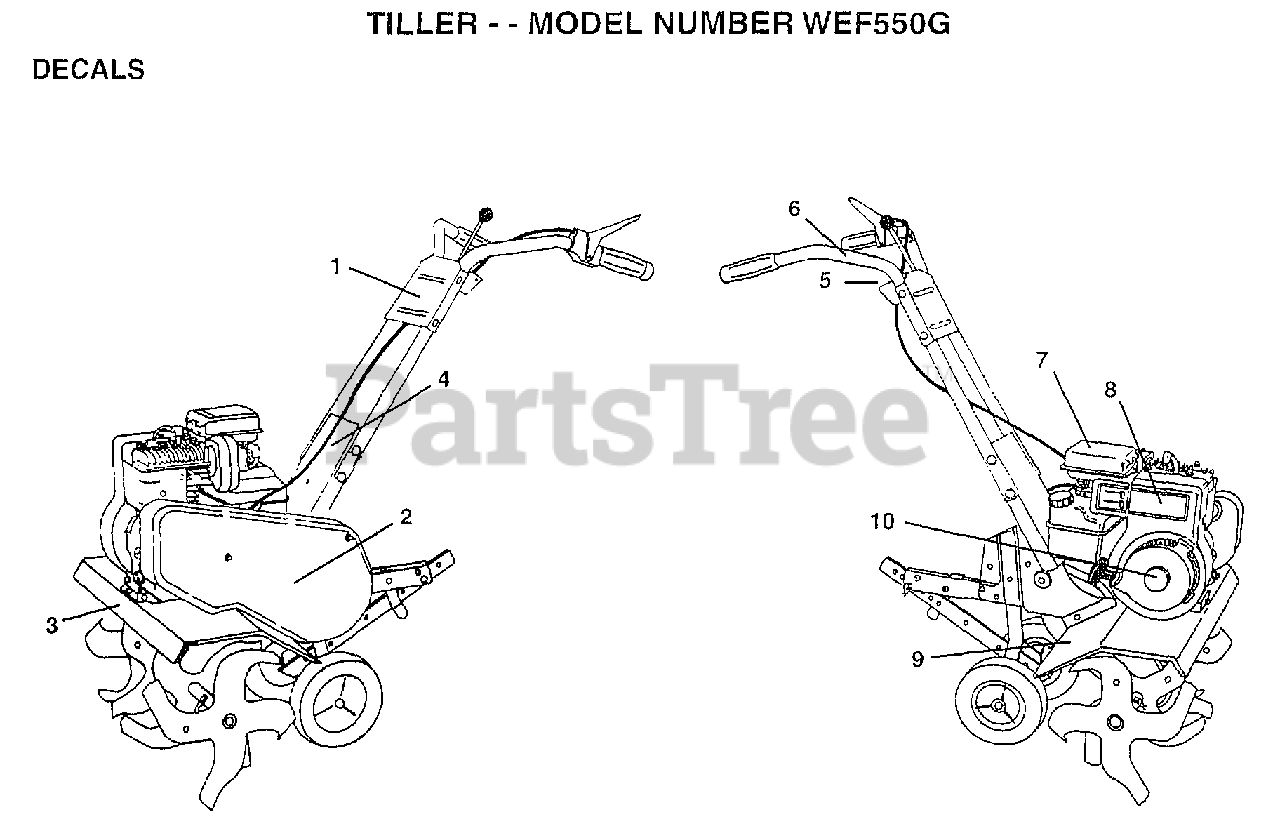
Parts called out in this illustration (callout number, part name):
1	"DECAL PANEL,CTRL"
2	"DECAL GUARD,BELT"
3	"DECAL SHIELD,TINE"
4	"DECAL PANEL,LOWER"
5	DECAL REVERSE
6	DECAL TI
7	DECAL TI
8	DECAL, BRIGGS & STRATTON
10	DECAL, 5 HP
